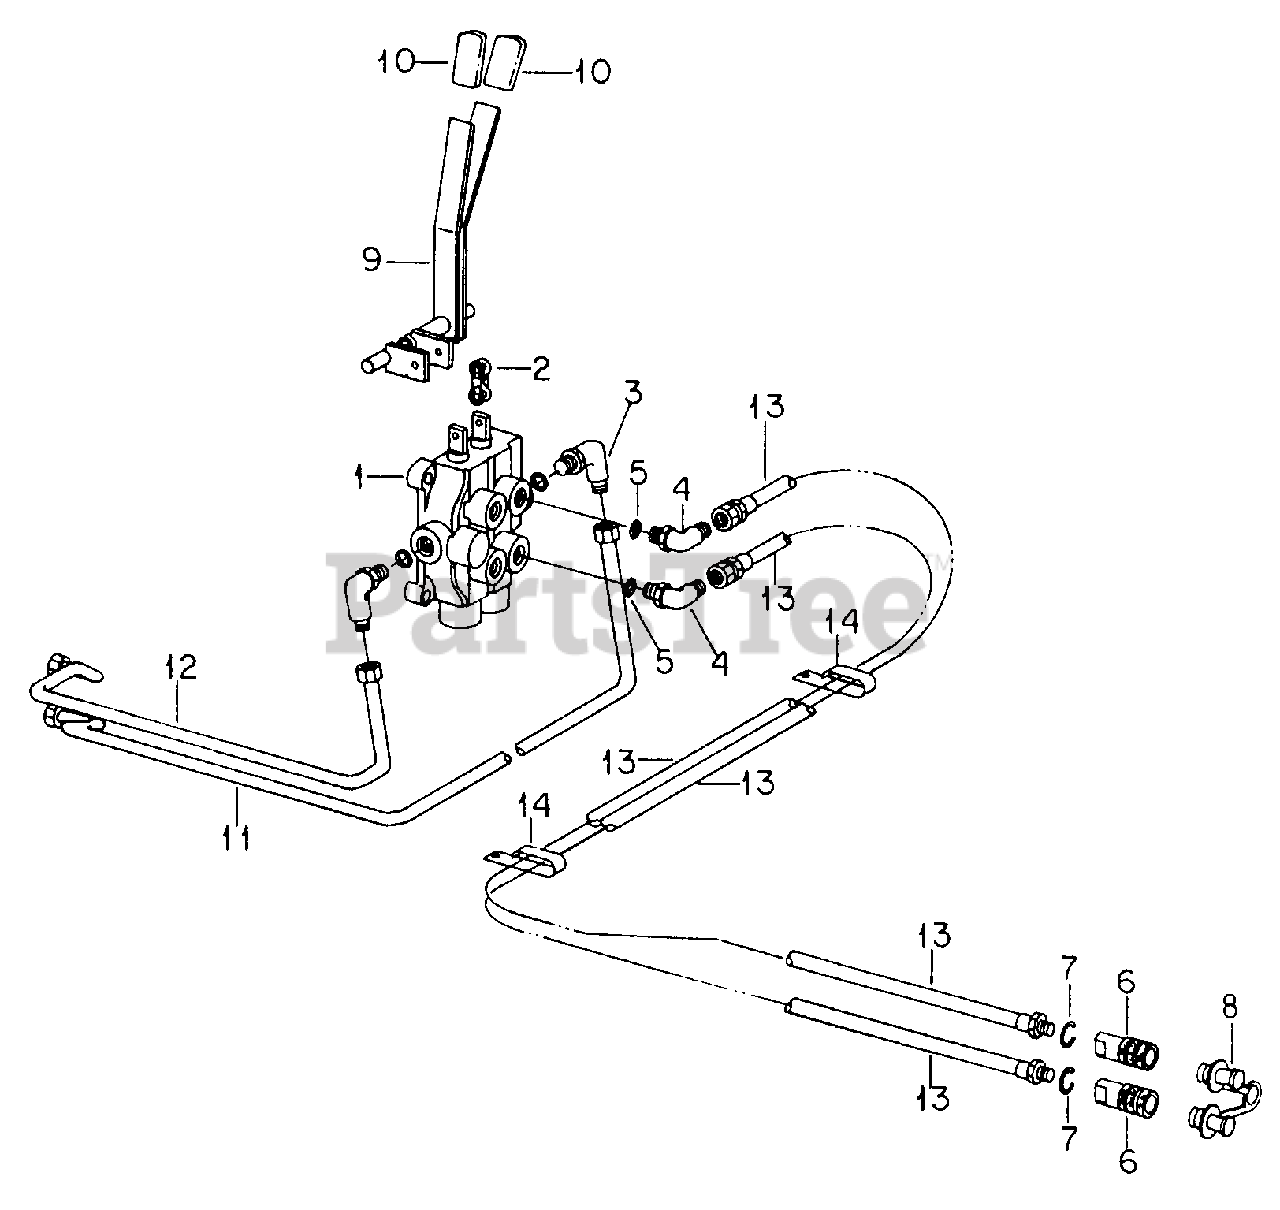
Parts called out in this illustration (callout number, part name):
1	Valve Assy, Control
2	Link, Chain
3	Elbow, 90 Deg Tube
4	Elbow, 90 Deg Tube
5	O-Ring, 3/8 OD Tube
6	Body, Hydraulic Coupling
7	Ring, External Retaining
8	Plug, Protective
9	Handle Assy, Valve
11	Tube Assy, Pressure
12	Tube Assy, Return
13	Hose, Pressure Supply
14	Not used in this application
